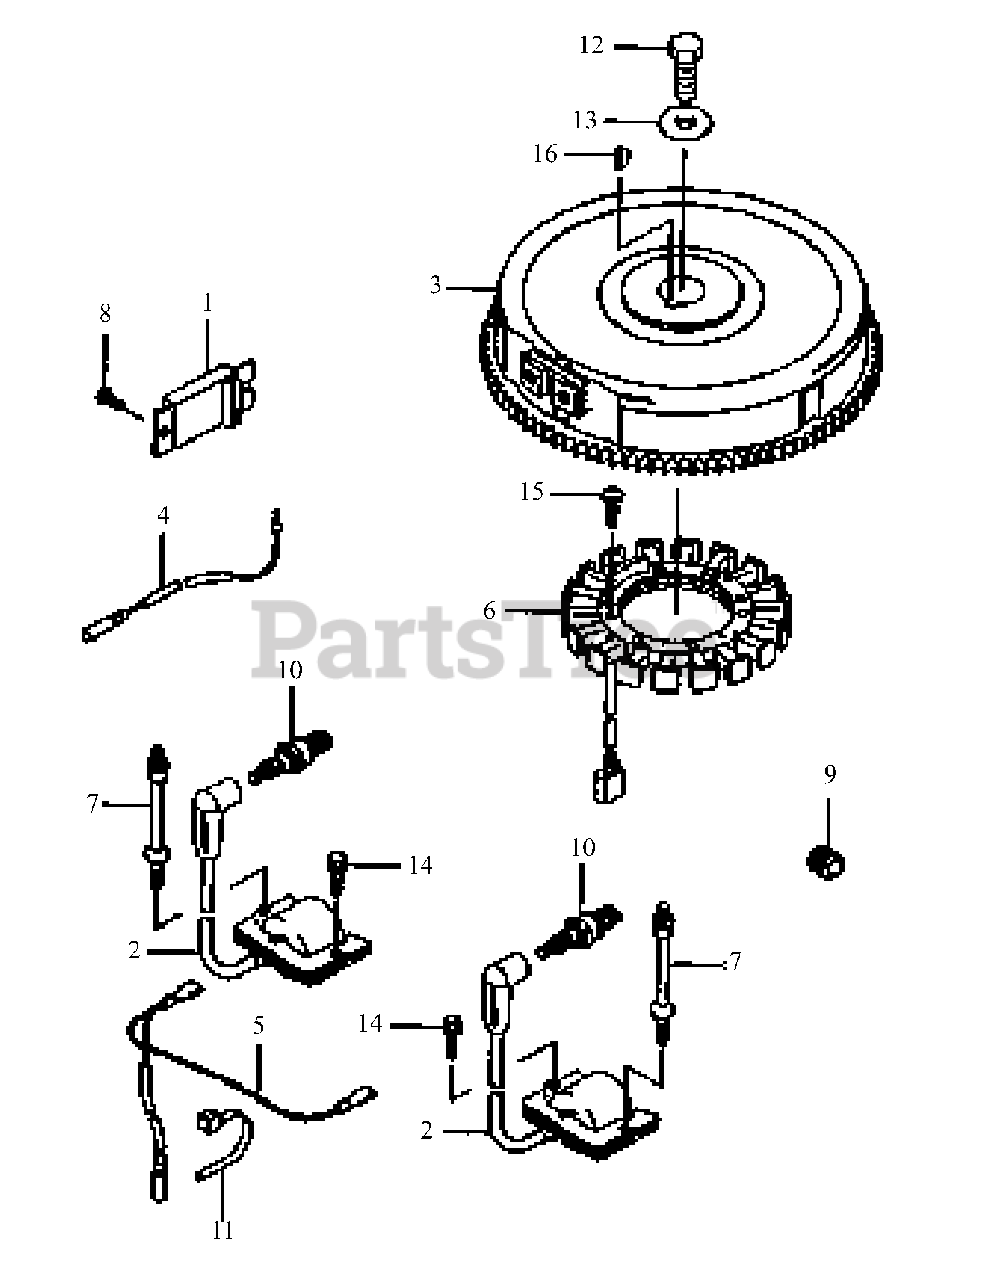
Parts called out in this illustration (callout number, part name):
1	Regulator-Voltage
2	Coil-Assy-Ignition
3	Flywheel-Assy
6	Coil-Charging
7	Stud
10	Spark Plug
12	Bolt, 12 x 30
15	Screw
16	Key-Woodruff
